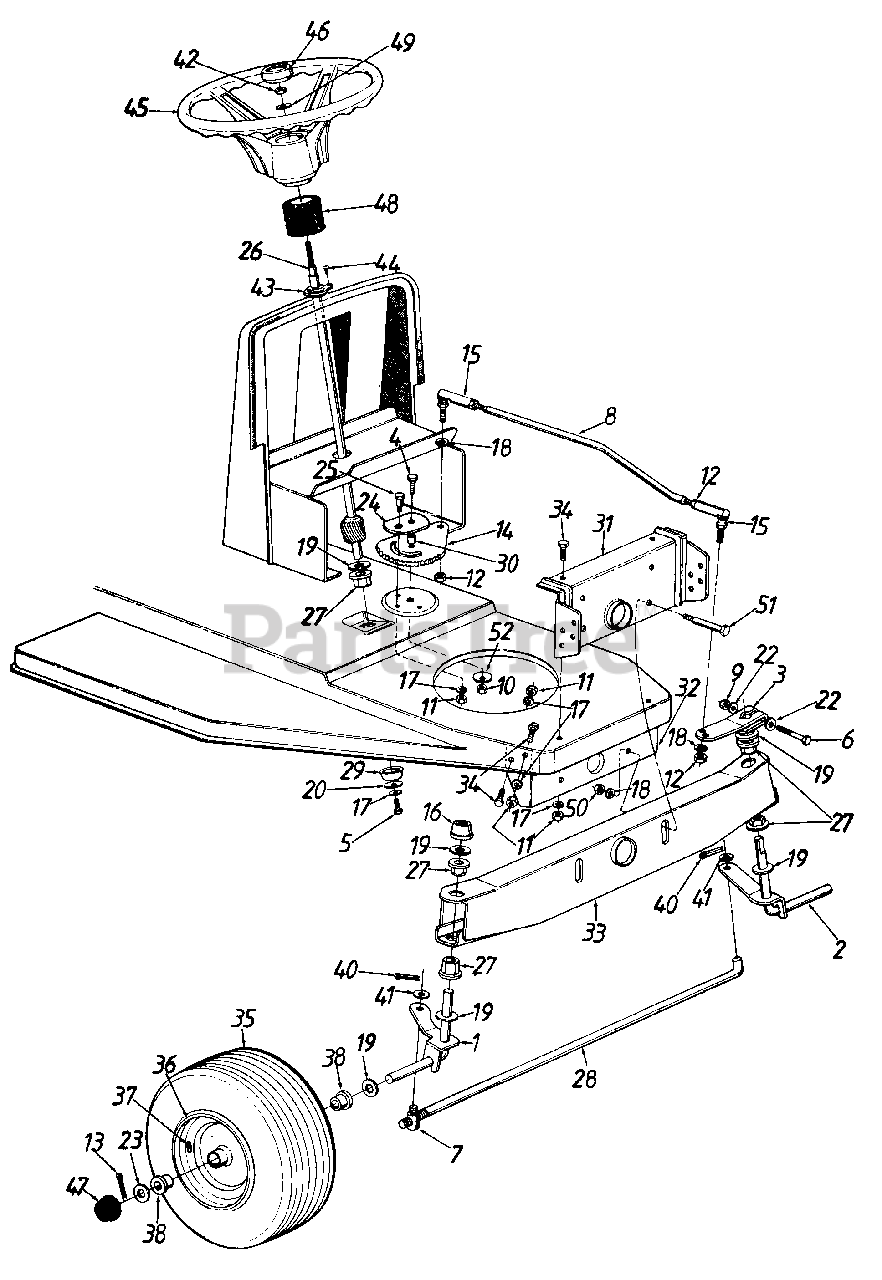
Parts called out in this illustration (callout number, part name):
1	Front Axle Ass'y.-R.H.
2	Front Axle Ass'y.-L.H.
3	Steering Arm
4	Hex Bolt 3/8-24 x 1" Lg.
5	Hex Bolt 5/16-18 x .62"
6	Hex Bolt 5/16-24 x 2" Lg.
7	Ferrule
8	Steering Drag Link
9	Hex L-Nut 5/16-24 Thd.
10	Hex Nut 3/8-24 Thd.
11	Hex Nut 5/16-18 Thd.
12	Hex Jam Nut 3/8-24 Thd.
13	Cotter Pin 1/8" Dia.
14	Steering Gear Segment
15	Drag Link Ball Joint 3/8-24 Thd.
16	Push Cap
17	L-Wash. 5/16" I.D.
18	L-Wash. 3/8" I.D.
19	Fl-Wash. .64" I.D. x 1.24"
20	Fl-Wash. .340" I.D. x 1.125"
22	Spr. Wash. .32" I.D. x .62"
23	Fl-Wash. .635" I.D. x 1.585"
24	Retainer Plate
25	Shld. Bolt .437" Dia. x .350"
26	Steering Shaft
27	Hex Flange Brg. .634" Dia.
28	Tie Rod 19.1" Lg.
29	Spacer.985" I.D.
30	Spacer.380" I.D.
31	Front Pivot Bar Support Brkt.
32	Rear Pivot Bar Support Brkt.
33	Pivot Bar Ass'y.
34	Hex Bolt 5/16-18 x .75" Lg.
35	Front Wheel Ass'y. Comp. 13" x 6"
37	Air Valve
38	Flange Bearing .632" I.D.
40	Cotter Pin 3/32" Dia.
41	Fl-Wash. .406" I.D. x .75"
42	Hex L-Nut 5/16-24 Thd.
43	Steering Column Brg.
44	Cr-Sunk Scr. #10 x 5/8" Lg.
45	Steering Wheel
46	Steering Wheel Cap
47	Hub Cap
48	Bellow Steering Column
49	Bell-Wash. .345" I.D. x .88"
50	Hex Nut 3/8-16 Thd.
51	Shld. Bolt 1/2" Dia. x 2.32"
52	Bell-Wash. .39" I.D. x 1.4" O.D.
